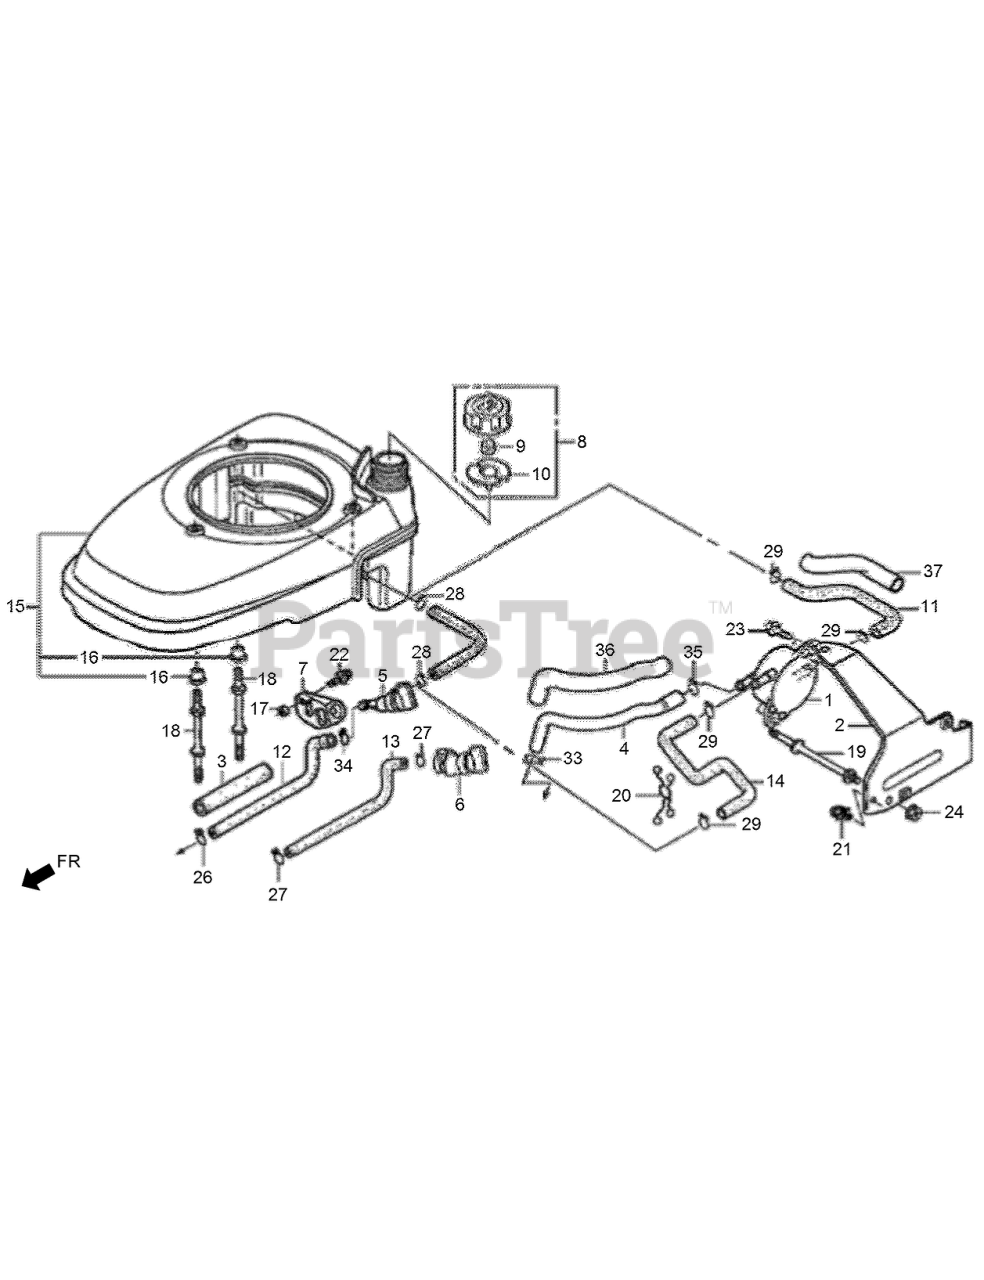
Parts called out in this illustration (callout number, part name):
1	PUMP ASM-FUEL
2	STAY-FUEL PUMP
3	RUBBER-SUPPORTER
4	TUBE-DIAPHRAGM
5	COCK ASM-FUEL (to S/N 1694818)
6	COCK ASM-FUEL (from S/N 1694819)
7	BRACKET-FUEL COCK (to S/N 1694818)
8	CAP ASM-FUEL TANK
9	SPONGE-FUEL CAP BREATHER
10	PACKING-FUEL CAP
11	TUBE-FUEL TANK
12	TUBE-FUEL (to S/N 1694818)
13	TUBE-FUEL (from S/N 1694819)
14	TUBE B-FUEL (to S/N 1963046)
14	TUBE B-FUEL (from S/N 1963047)
15	FAN COVER ASM (NH1)
16	COLLAR-FAN COVER
17	COLLAR-FR WINKER
18	BOLT-STUD
19	BOLT-STUD
20	CLIP-PURSE LOCK
21	CLIP-WIRE HARNESS
22	SCREW-WASHER-5X10
23	SCREW-WASHER-5X14
24	NUT-FLANGE-6MM
26	CLIP-TUBE (to S/N 1694818)
27	CLIP-TUBE (from S/N 1694819)
28	CLIP-TUBE
29	CLIP-TUBE
33	CLIP-TUBE
34	CLIP-TUBE (to S/N 1694818)
35	CLIP-TUBE
36	TUBE-VINYL-9X11X210
37	TUBE-VINYL-11X13X100
